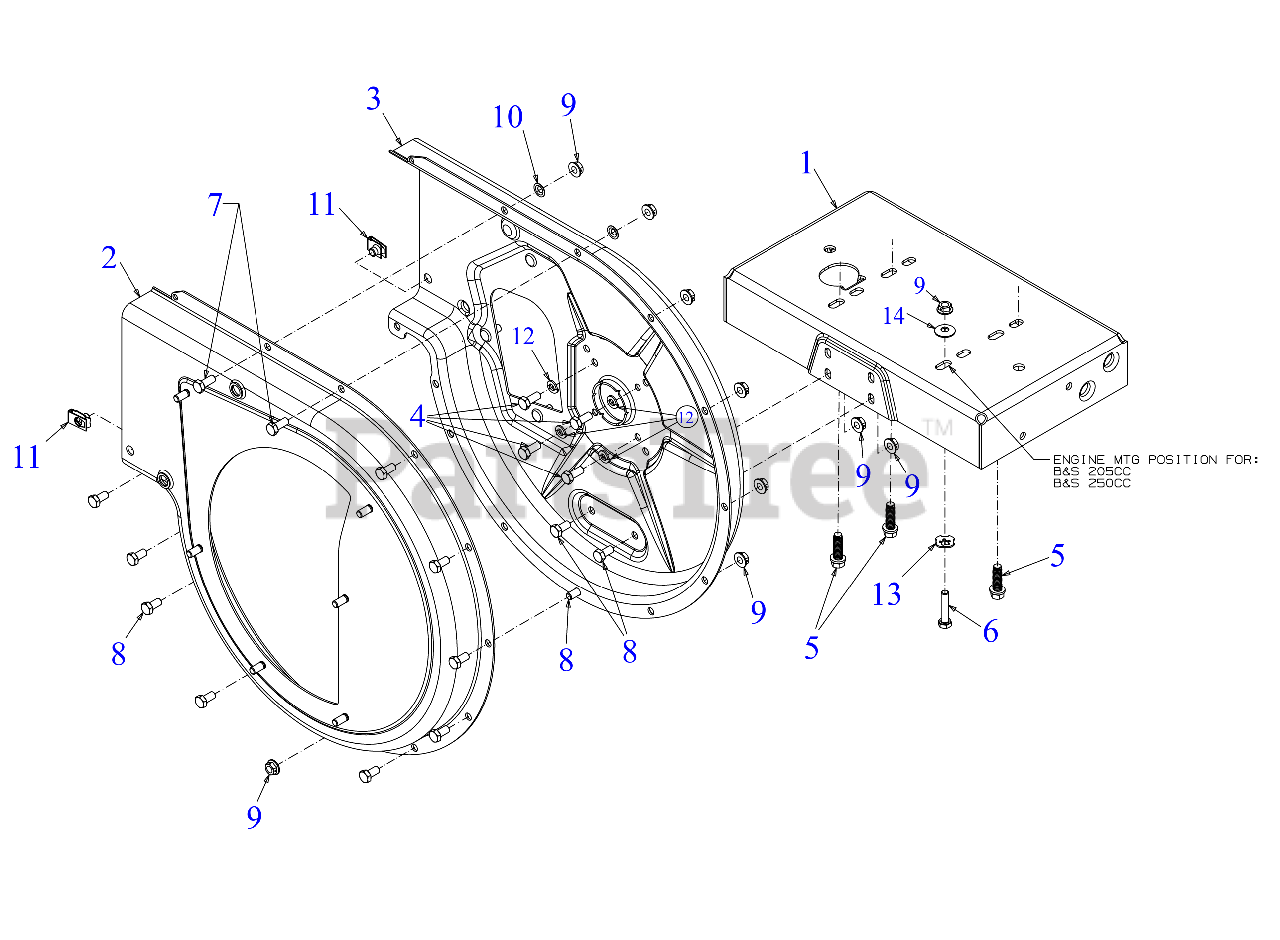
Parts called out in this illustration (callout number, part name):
4	HEX SCREW 5/16-24 x .75
5	SCREW 3/8-16 x 1.250
6	SCREW 5/16-18 x 1.5 LG
7	SCREW 5/16-18 x .75 GR5
8	SCREW 5/16-18X .625 GR5
9	HEX FLANGE NUT
11	U-NUT
12	LOCK WASHER 5/16
13	SPECIAL WASHER
14	BELL WASHER .337 X.867 x .057
